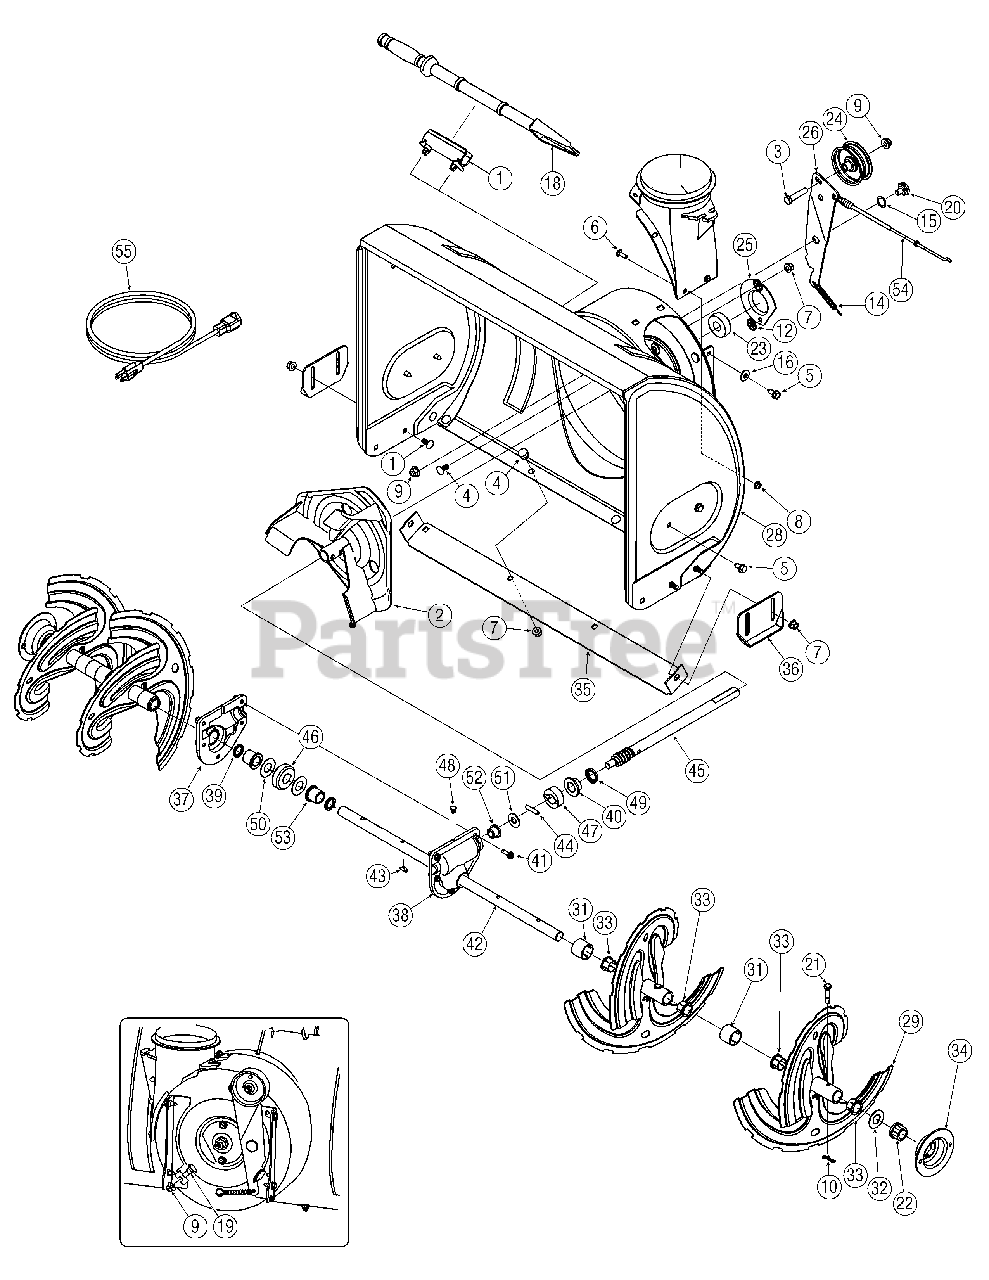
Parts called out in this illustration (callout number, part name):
1	Snow Removal Tool Mount
3	Hex Screw, 3/8-16, 1.75, Gr5
4	Bolt, Carriage, 5/16-18, .750 Gr1
5	Screw, 5/16-18, 0.625
6	Screw, Carriage, 1/4-20, .750, Gr5
7	Nut, Flange Lock, 5/16-18, Nylon
8	Nut, Flange Lock, 1/4-20, Nylon
9	Nut, Flange Lock, 3/8-16, Nylon
10	Cotter Pin, Bow-tie
11	Cable, Tie, 3/16 x .05 x 7.4
12	Nut, Push-on, .25 Dia
13	Chute, Adapter 5" Dia
14	Spring, Extension, .38 OD x 3.6
15	Washer, Wave, .625 x .885 x .
16	Washer, 349 x .879 x .063
17	Washer, Flat, .25 x .630 x .
18	Snow Removal Tool
19	Screw, Shoulder, .498 x .340,
20	Screw, Shoulder, .625 x .17, 3/8-
21	Shear Pin, .25 x 1.50
22	Bearing, Hex Flange x .75 ID
23	Bearing, Ball, .75 ID x 1.85 OD
24	Flat Pulley, Idler, 2.75 OD
25	Housing, Bearing, 1.85 ID
27	Gearbox Assembly, Auger, 24"
31	Spacer, 1.25 OD x .75 ID x 1.
32	Washer, Flat, .76 x 1.49 x .06
33	Bushing, Flange, .800 ID x .910
37	Housing, Auger, RH Reduced
38	Housing, Auger, LH Reduced
39	Seal, Oil, .750 ID
40	Bearing, Flange, .75 ID x 1.00
41	Screw, Self-tapping, 1/4-20, 0.750
42	Axle, Auger, 24"
43	Key, Hi-pro 3/16 x 5/8
44	Pin, Dowel, .25 OD x 1.2
45	Shaft, Worm .75 OD
46	Gear, Worm 20T
47	Collar, Thrust
48	Plug, 1/4 x .437
49	Seal, Oil, .75 x 1 x .131
50	Washer, Flat, .760 ID x 1.5 OD
51	Washer, Flat, .51 x 1.12
52	Bearing, Flange, .75 ID x 1.00
53	Bearing, Flange, .75 ID x 1.00
54	Clutch Cable, Auger, 47.23"
55	Extention Cord, 110V
